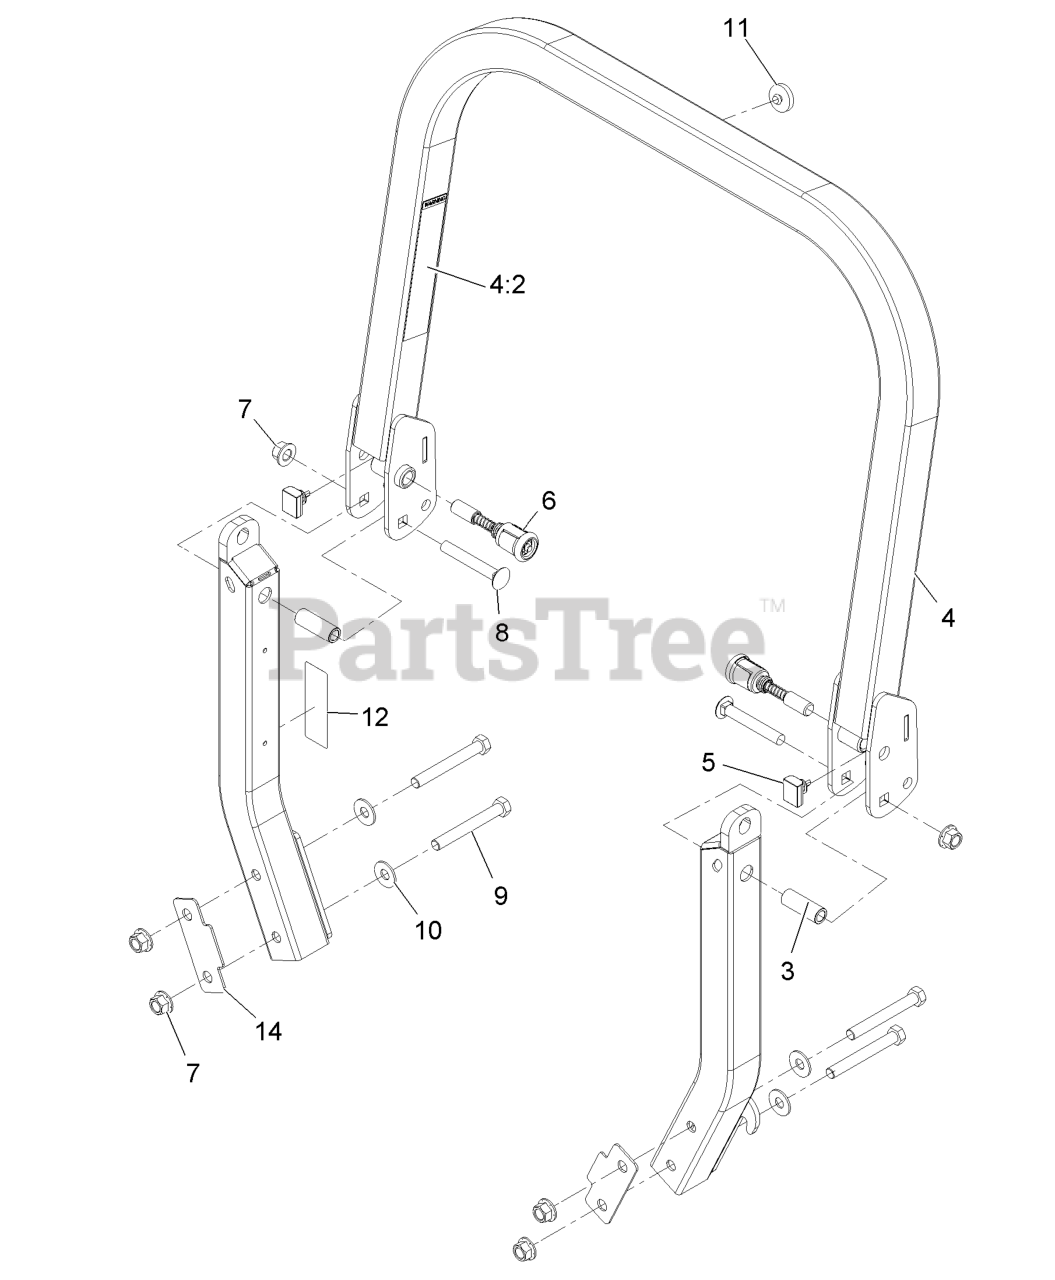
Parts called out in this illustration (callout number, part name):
4	UPPER ROPS ASM
4:2	DECAL-WARNING, FOLDING RO
5	BUMPER-ROPS
6	PIN-SPRING
7	Nut-Lock 1/2-13
8	SCREW-CARR
9	SCREW-HH
10	WASHER-SPRING
11	BUMPER-PUSH-IN, RUBBER
12	DECAL-CAUTION
